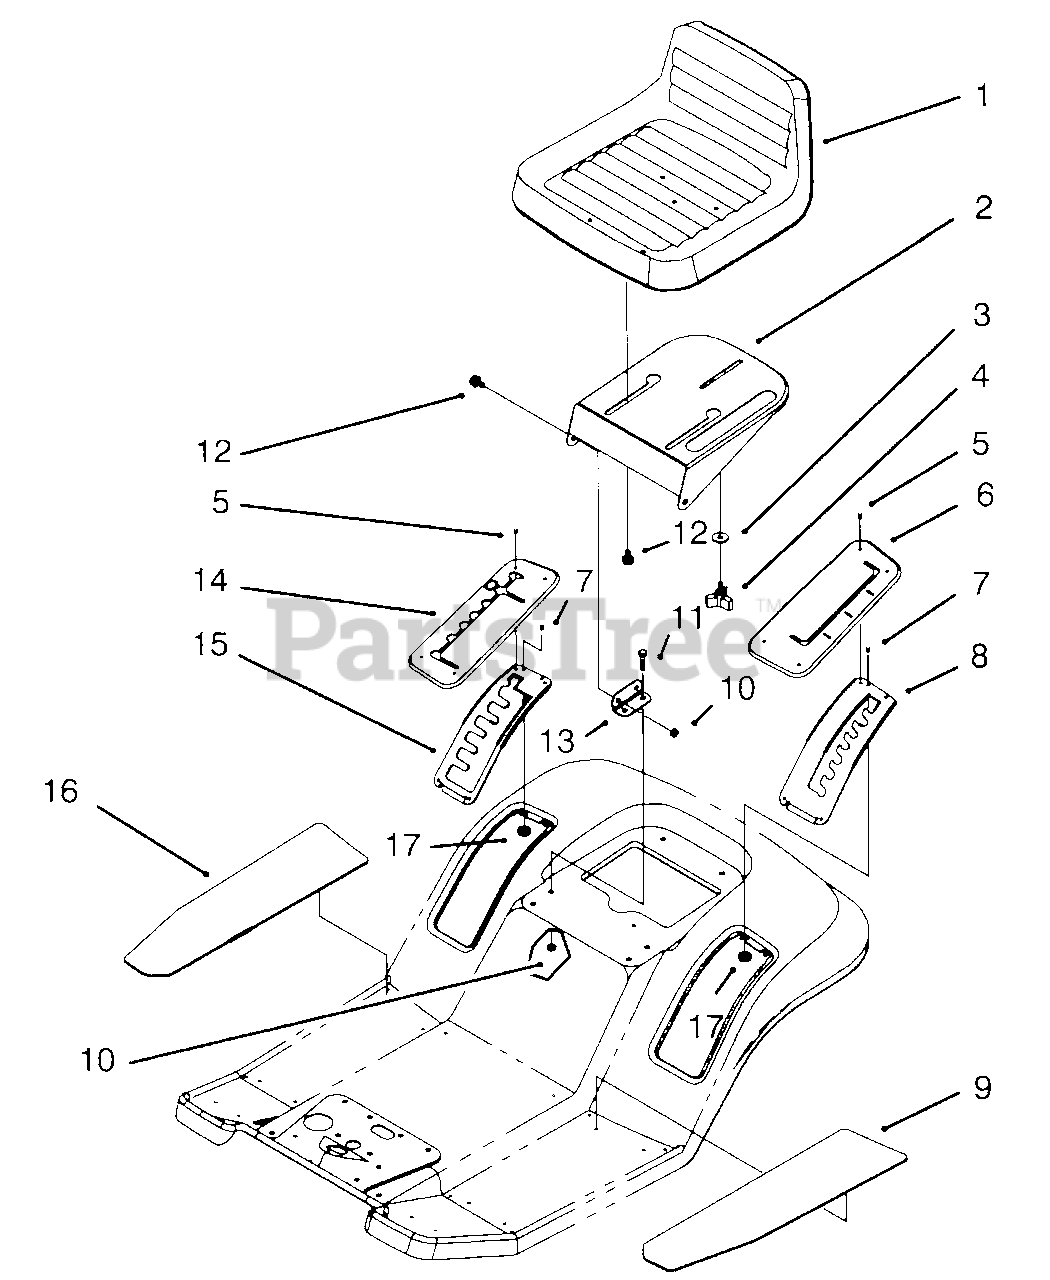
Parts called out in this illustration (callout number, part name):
1	Seat (Model No. 81182 Only)
2	Support-Seat
3	Washer-Fender
4	Knob-Studded
5	Panel-Fastener
6	Cover-H.O.C.
7	Rivet-Pop
8	Gate-H.O.C.
9	Tread-L.H. Foot
10	Nut-Lock
11	Screw-Hex Hd. Cap
12	Bolt-Shoulder
13	Bracket-Seat Hinge
14	Cover-Shift Gate
15	Gate-Shift
16	Tread-R.H. Foot
17	Washer-Backup
